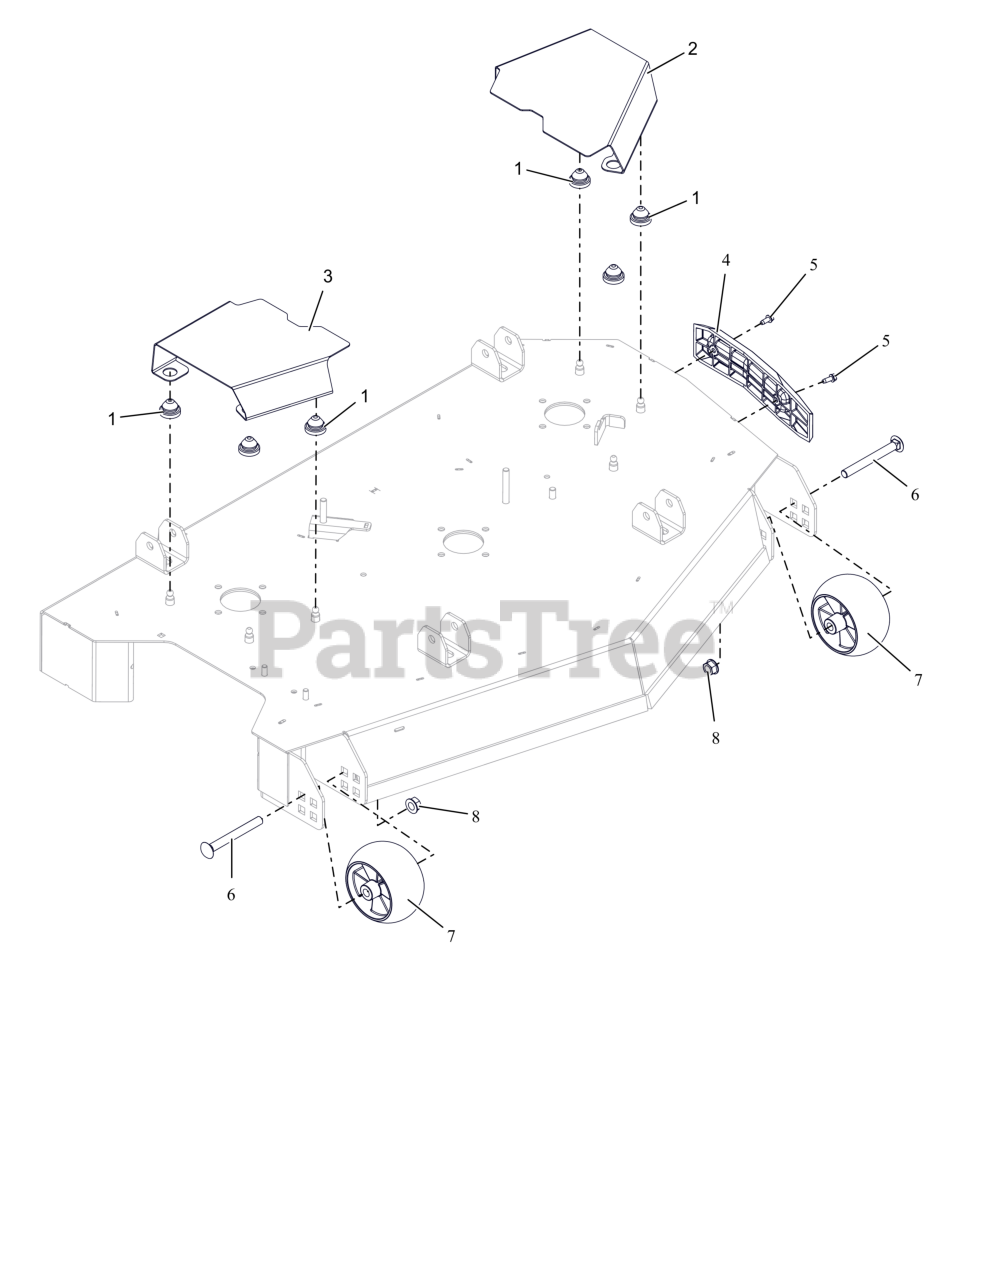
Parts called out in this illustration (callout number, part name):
1	COUPLING, RUBBER PUSH-IN
2	COVER- BELT
3	COVER- RIGHT BELT
4	BUMPER- DECK
5	SCR,TAP .25-20X.625 HWH ZCC
6	BLT,RHNS .50-13X4.50 G5 ZCC NS
7	WHEEL, ANTI SCALP - 5X3 CTR W/RIBS
8	NUT-LK-CTR-FLG .500-13 GG ZCC
